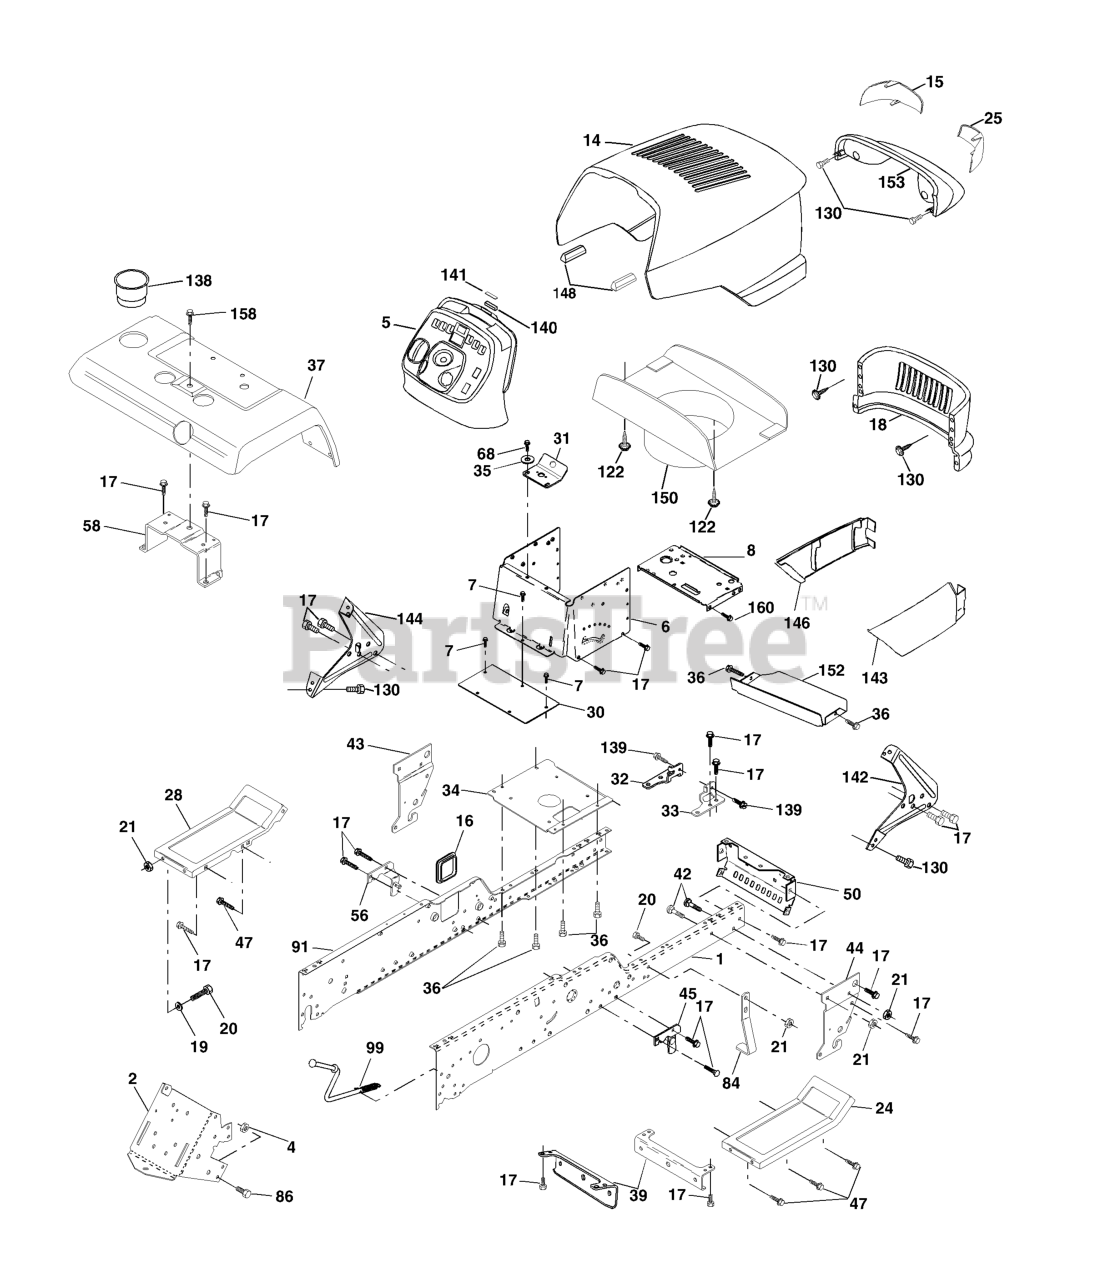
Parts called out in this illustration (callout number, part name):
1	RAIL, FRAME RH
2	DRAWBAR, GT
4	Nut, Crown Lock 7/16-14 Unc
5	DASH.STEALTH.YTGT.2CYL.BLK
6	DASH VGT, LOWER
7	SCREW
8	SUPPORT, BATTERY
14	HOOD ASM.
15	LENS LH
16	COVER ACCESS
17	SCREW 3/8-16X3/4
18	GRILLE
19	WASHER
20	BOLT
21	NUT
24	FOOTREST RH
25	LENS RH
28	FOOT REST LH
30	SADDLE.HYDRO.95
31	BRACKET SUPT 1-PC VGT STEERING
34	PLATE ASM ENG CHASSIS
35	WASHER
36	SCREW 5/16"
37	FENDER
39	BRACKET AXLE, FRONT
42	BOLT D
43	FRONT SUSPENSION BRKT LH
44	FRONT SUSPENSION BRKT RH
45	BRACKET SUSP RH
47	SCREW LT
50	BRACKET, CHASSIS FRONT
56	BRACKET ASM, SUSP CHASSIS
58	BRACKET ASM, FENDER
68	Screw, 5/16-18 x 1/2
84	MOWER STOP
86	BOLT
91	RAIL, FRAME LH
99	ROD ASM, BYPASS
122	SCREW.HEX.WS.HD.8-18 X 7/8
130	SCREW
138	CUPHOLDER
139	BOLT, SHOULDER 5/16-18
140	MAGNET STEALTH
141	STRIKER PLATE
142	BRACKET DASH STEALTH(R)
143	SKIRT GRILLE RH
144	BRACKET DASH STEALTH LH
146	SKIRT GRILLE LH
148	EXTRUSION BUMPER (3 2) (2 2)
150	DUCT HEAT HOOD
152	BROWNING SHIELD
153	LENS, HEADLIGHT BAR
158	SCREW 3/8-16X1/2
160	SCREW 5/16-18X1/2"
